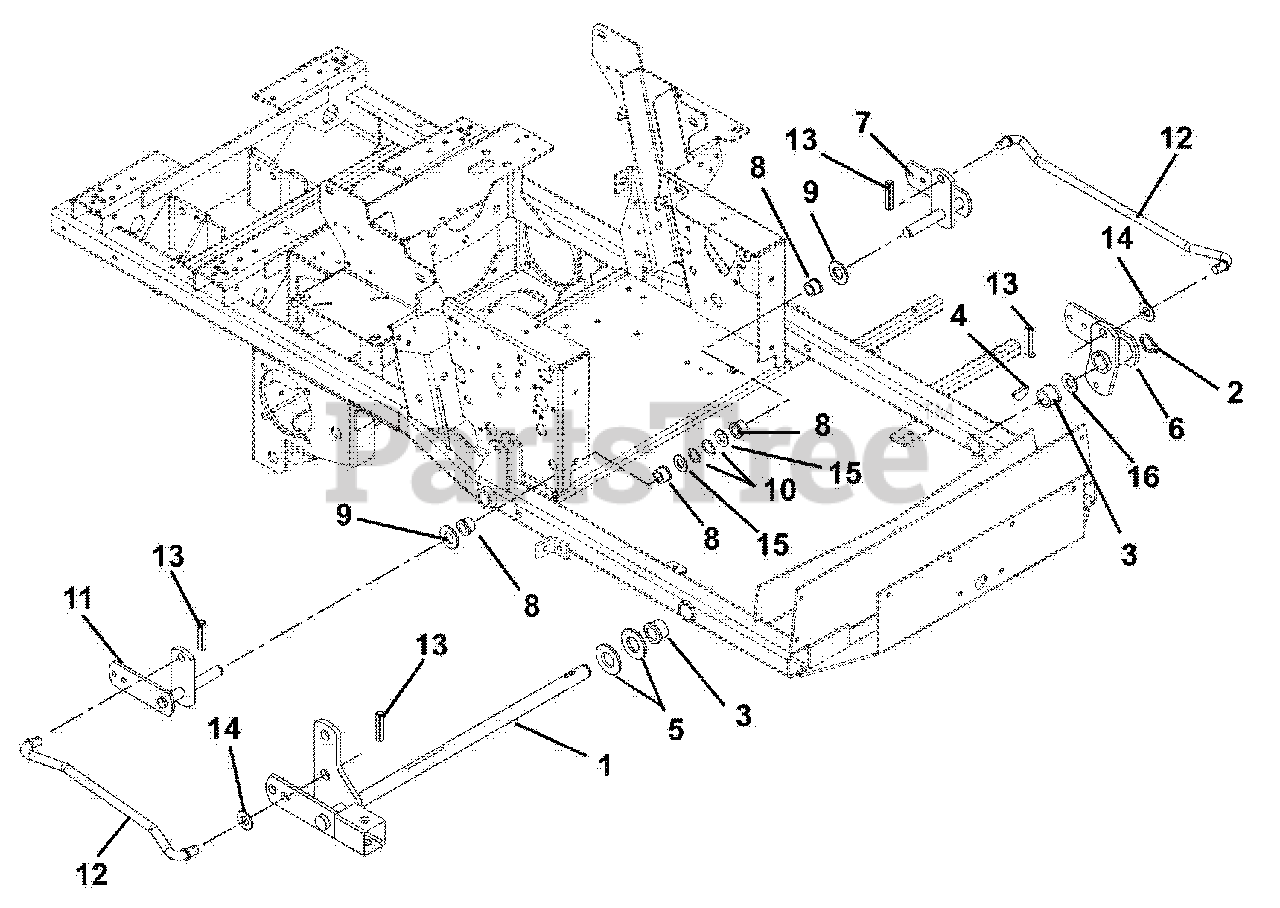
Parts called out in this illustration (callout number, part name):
1	Lift, Mower
2	Ring, Retaining External 1.00 x .078
3	Bushing, Flange 1.00 x 1.12 x .75 x 1.375
4	Key, Woodruff .25 x 1.00
5	Washer, Flat Steel 1.062 x 2.00 x .134
6	Weldment, Lift Arm-Front
7	Weldment, Rear Lift Arm-Left Hand
8	Bushing, Flange Nylon .762 x 1.0 x .58 x 1.48
9	Washer, Hardened Steel .758 x 1.23 x .031
10	Ring-Retaining-External .689 x .077
11	Weldment, Rear Lift Arm- Right Hand
12	Rod, Lift Assist 19.35"
13	Pin, Roll .25 x 1.25 Stainless Steel
14	Washer, Flat Steel .630 x 1.25 x .062
15	Washer, Flat Steel .755 x 1.25 x .125
16	Washer, Hardened Thrust 1.00 x 1.55 x .03
